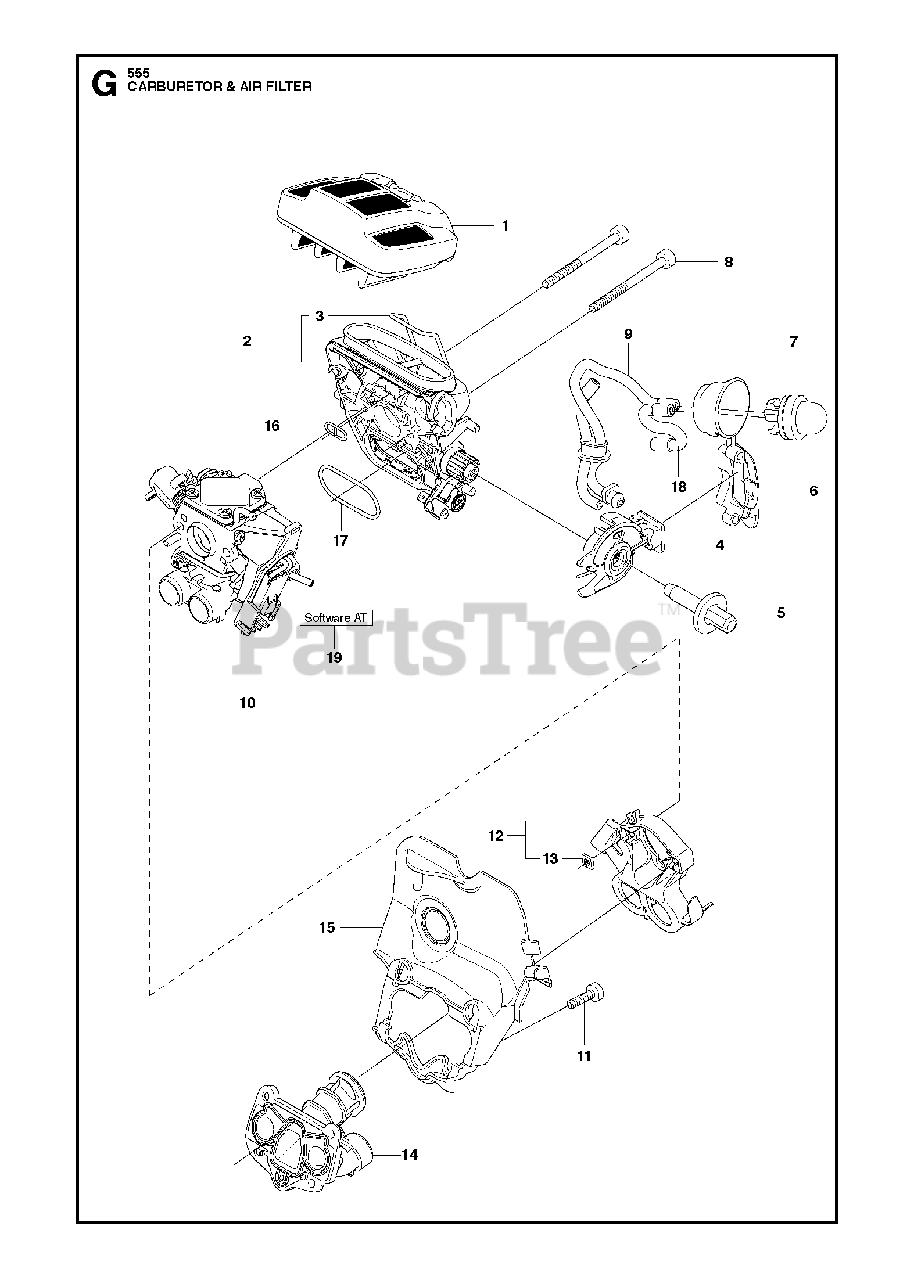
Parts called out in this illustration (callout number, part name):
1	AIR FILTER ASSY
2	RP FILTER HOLDER ASSY
3	SHACKLE
4	CHOKE CONTROL ASSY
7	AIR PURGE BUBBLE
9	FUEL HOSE
10	CARBURETTOR
11	SCREW IHSCM
13	NUT
14	RP INLET PIPE
15	INTERMEDIATE WALL
